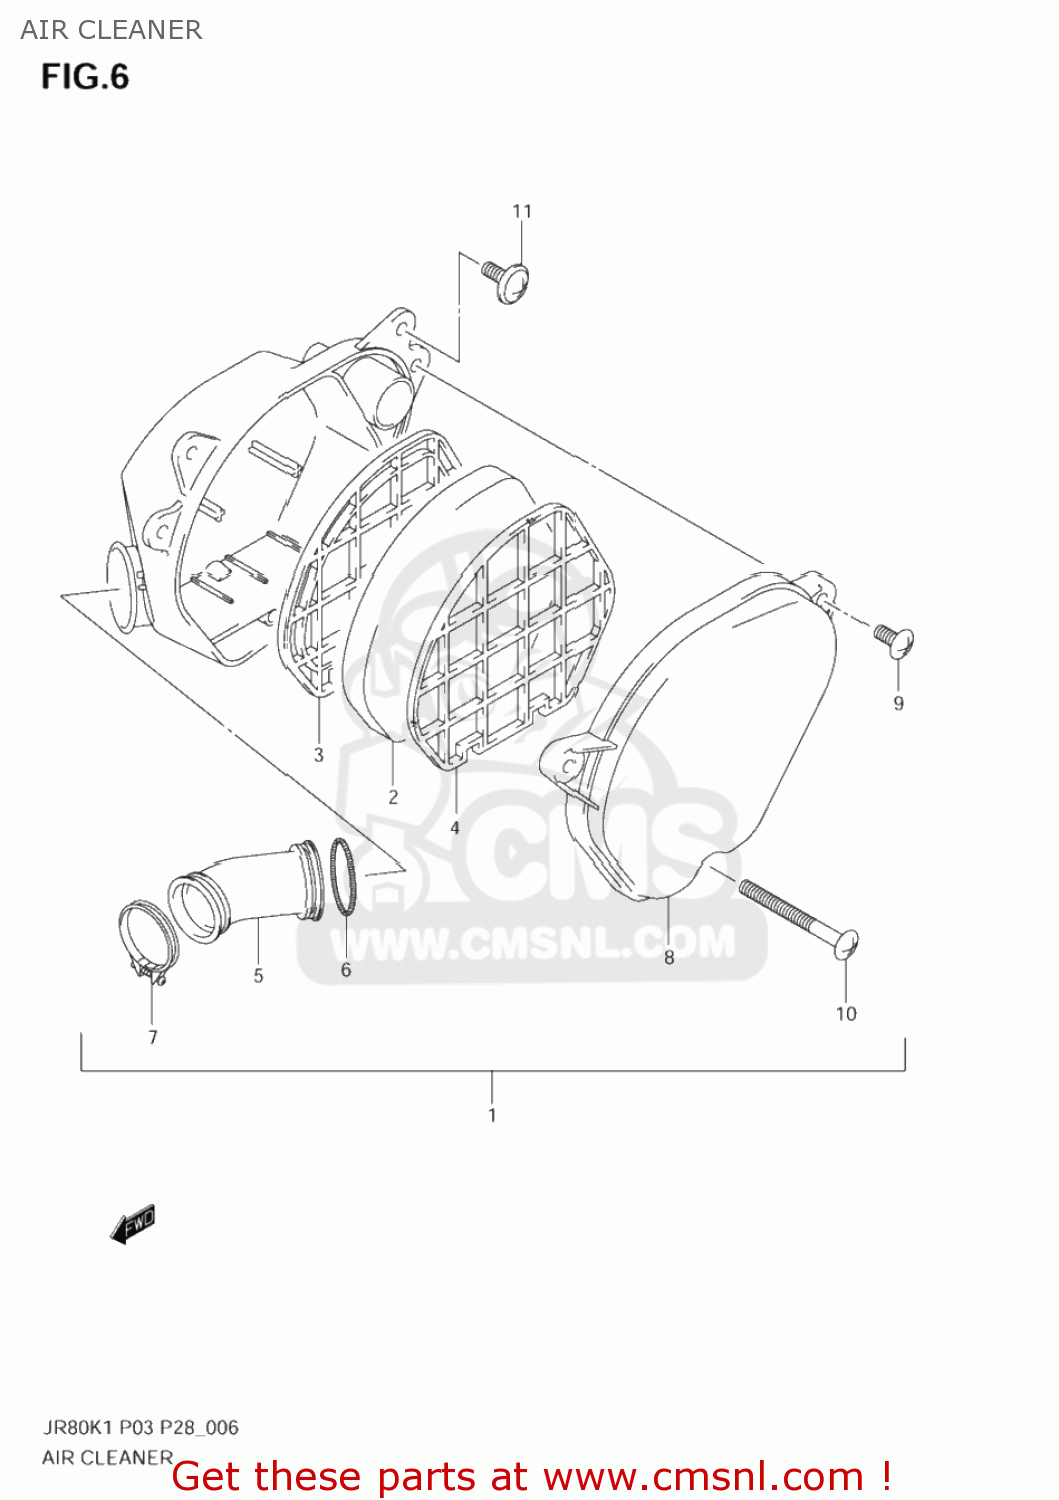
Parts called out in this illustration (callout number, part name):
1	CLEANER ASSY,AIR
2	FILTER
3	HOLDER,FILTER INNER
4	HOLDER,FILTER OUTER
5	TUBE,OUTLET
6	SPRING,AIR CLEANER SIDE
7	CLAMP
8	CAP,CLEANER
9	SCREW
10	SCREW
11	SCREW(6X16)
